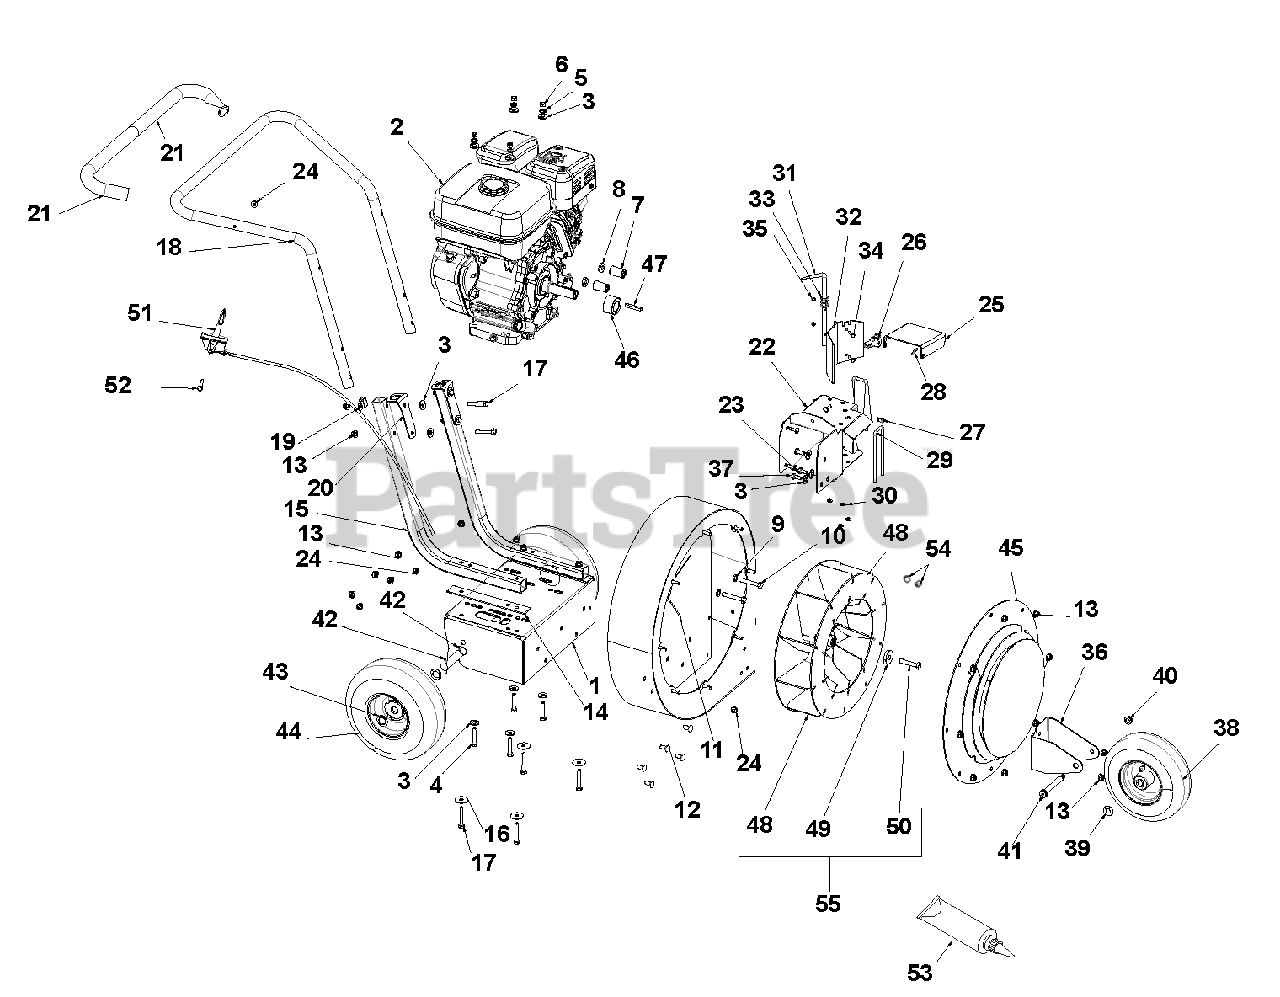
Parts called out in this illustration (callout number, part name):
1	WMT-BLOWER FRAME, SM
2	ENGINE,SUBARU 9HP EX27 (CARB)
3	@WSHR-FL-STL.38X.875X.083 YWZC
4	@BLT-HEX .31-18X1.75 GR5 YWZC
5	WSHR-LK .312X.097 HVY YWZC
6	@NUT-HEX .31-18 YWZC
7	SPACER, .38X.875X1.38
8	WSHR-FL-STL .390X.88X.18 YWZC
9	@WSHR-LK .38X.094 REG YWZC
10	@BLT-HEX .38-16X2.25 GR5 YWZC
11	WMT-BLOWER HOUSING MED
12	@BLT-RDHDSQNK .31-18X.75 G5YZ
13	@NUT-LK-NYL-FLG .31-18 YWZC
14	SPACER-RUBBER
15	TUBE-HANDLEBAR, LOWER SQ
16	WSHR-FL-STL .347X1.254X.048YWZ
17	@BLT-HEX .31-18X2.00 GR5 YWZC
18	TUBE-HANDLEBAR, UPPER
19	J-CLAMP
20	BRKT-HANDLEBAR MOUNT
21	GRIP-HANDLEBAR, UPPER
22	WMT-OUTLET CHUTE MED
23	@BLT-HEX .25-20X.75 GR5 YWZC
24	@NUT-LK-NYL-FLG .25-20 YWZC
25	BRKT, OUTLET DOOR
26	KNOB,WING .31-18 UNC NYL/TALC
27	PIN-CLEV .313X.500 YWZC
28	PIN-HAIR, ENDRIES #25 YWZC
29	WIREFORM-GUARD, SAFETY
30	NUT-PUSH .25X.50 O.D.
31	WIREFORM-LEVER, DIRECTION
32	BRKT-FLAP, DIRECTION
33	SPRING-COMP 1.0LX.72 OD .05DIA
34	@SCR-MCH 10-24X.75 HWH YWZC
35	@NUT-LK-NYL 10-24 W/INSRT YWZC
36	BRKT-WHEEL, FRONT
37	@BLT-HEX .31-18X.75 GR5 YWZC
38	WHEEL-9X2.5 PNEU- WHITE RIM
39	WSHR-FL-NYL .518X1.000X.080
40	@NUT-LK-TOP-FLG .38-16 YWZC
41	BLT-SHLDR .5X3.25X.38-16
42	@PIN-CTR .16X1.25 EXTPRSQCT YZ
43	WSHR-FL-STL.754X1.125X.062YWZC
44	WHEEL-10X3.75 PNEU. WHITE
45	WMT-INLET GUARD MED
46	BSHG-SLV, 1.0X1.75X1.0
47	KEY-STR .25X1.75X.25
48	WMT-FAN, MED W/SET SCRS
49	WSHR-FL-STL.463X1.375X.25 YWZC
50	BLT-HEX .44-20X2.00 G5 YZ EP80
51	THROTTLE CONTROL
54	SCR-SET .31-18X.38 SKHCUPDL
55	KIT-9HP FAN REPLACEMENT
